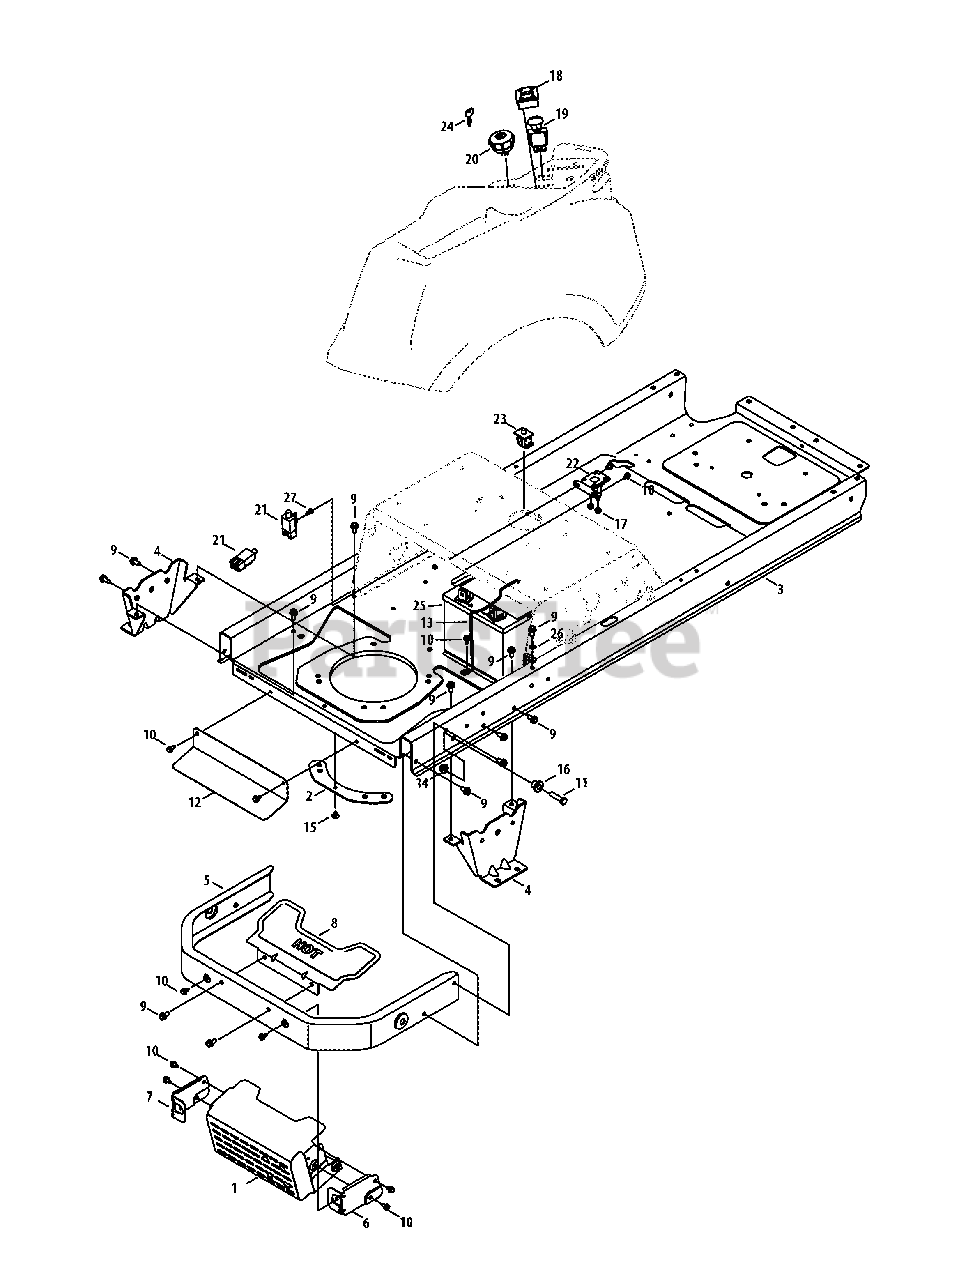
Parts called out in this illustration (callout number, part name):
1	ASSEMBLY, Muffler Shield
2	PLATE, Retainer
3	SCREW, .498 DIA. X 1.296, Shoulder
4	BRACKET, Transmission Mounting
5	BUMPER, Rear
6	BRACKET, Muffler Mounting Shield, RH
7	BRACKET, Muffler Mounting Shield, LH
8	SHIELD, Muffler
9	SCREW, 5/16-18 X .750, Hex Washer
10	SCREW, 1/4-20 X .625, Hex Washer
11	SCREW, 3/8-16 X 1.25, Hex
12	SHIELD, Lower Heat
13	ROD, Battery
14	NUT, 3/8-16, Flanged Lock, GR5, Zinc/Clear
15	CLIP, .250 DIA. X .500 LG
16	SPACER, .38 X 1.0 X .70, Shoulder
17	NUT, Nylock Flanged, 1/4-20
18	HOUR METER/SERVICE MINDER
19	SWITCH, Electric PTO
20	SWITCH, Key (Ignition)
21	SWITCH, Interlock
22	SOLENOID
23	SWITCH, Seat
24	ASSEMBLY, Key
25	BATTERY
26	WASHER, 5/16, EXT., Lock
27	SCREW, #10-32 X .500, Shoulder
